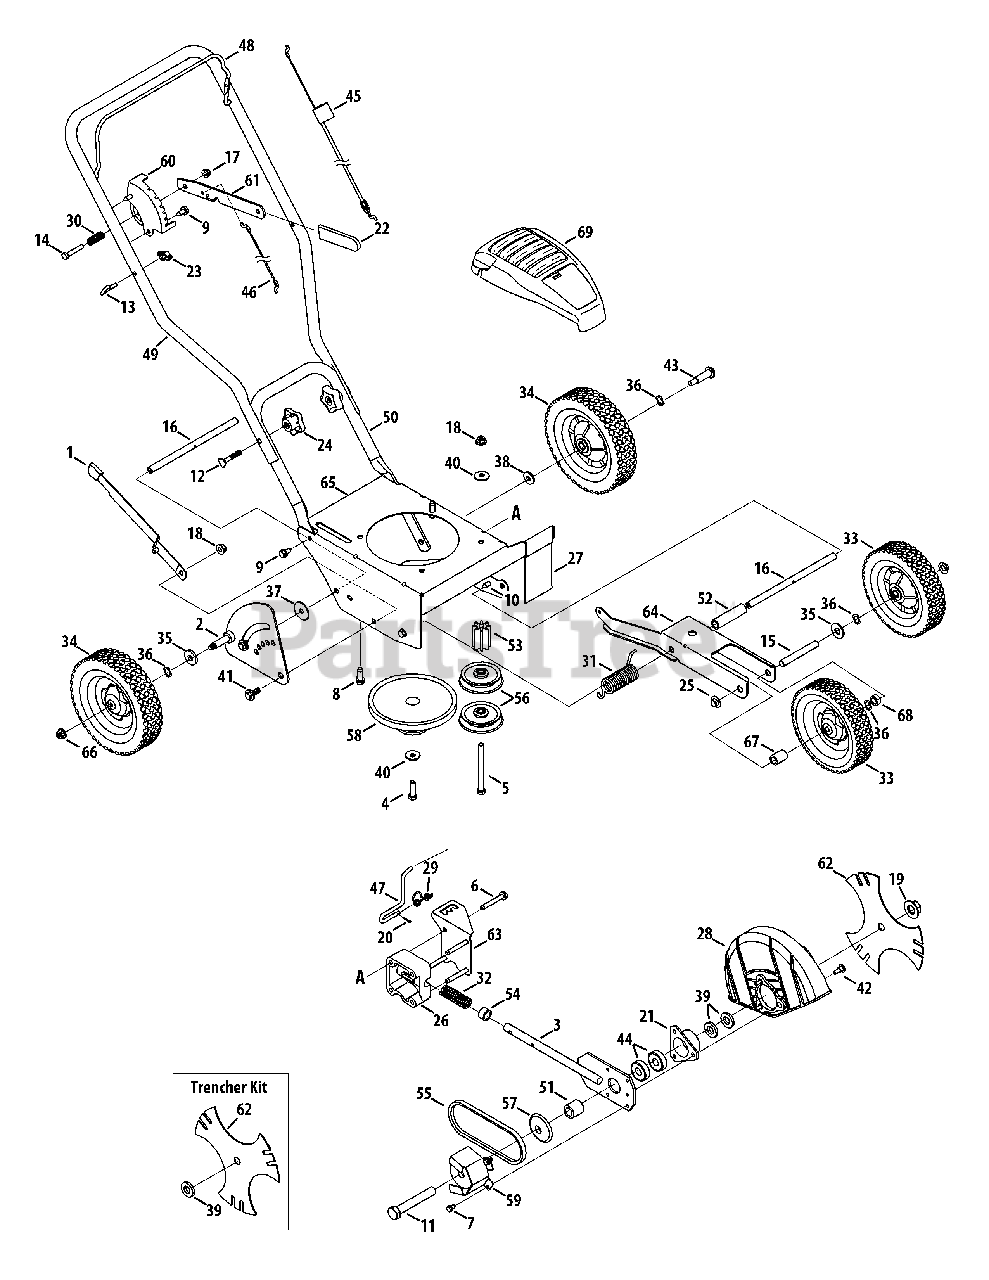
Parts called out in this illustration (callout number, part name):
1	Curb Height Adjustment Lever
2	Curb Height Adjuster Plate
3	Blade Plate Assembly
4	Screw 3/8-24
5	Screw 3/8-16
6	Hex Screw, 5/16-18
7	Self-tapping Screw, 1/4-20
8	Screw, 3/8-16
9	Hex Screw, 5/16-12
10	Hex Screw 5/16-18
11	Hex Screw, 5/8-18
12	Carriage Bolt, 5/16-18
13	Rope Guide (Eye Bolt)
14	Hex Screw, 5/16-18
15	Axle Shaft .50x6.65
16	Frame Spacer .50x9.25
17	Lock Flange Nut, 5/16-18
18	Flange Nut 3/8-16
19	Flange Nut, 5/8-18
20	Clevis Pin 3/32 x .625
21	Bearing Cup
25	Push Cap 1/2" rod
26	Bearing Block
27	Debris Guard
28	Blade Guard
29	Double Torsion Spring
30	Compression Spring
31	Torsion Spring
32	Compression Spring
33	Wheel 7 x 1.75 T-Tread
34	Wheel 8 x 1.75 T-Tread
35	Flat Washer, .531 x 1.25 x .181
36	Wave Washer .531 x .781 x .013
37	Flat Washer, .385 x 1.5 x .075
38	Flat Washer .385 x 1.0 x .135 †
39	Flat Washer .635x1.24x.181
40	Bell Washer,.396 x 1.140
41	Shoulder Screw, 3/8-16
42	Shoulder Screw
43	Shoulder Screw, 3/8-16
44	Bearing, .625 ID x 1.57 OD
45	Control Cable
46	Wheel Adjustment Cable
47	Blade Adjustment Rod
48	Bail Handle
51	Spacer, .63 x 1.12 x 1.06
53	Pulley Mount Spacer
54	Spacer, .64 x.88 x .50
56	Flat Idler Pulley, 2.5 OD
58	Combination Flywheel Pulley
61	Depth Index Lever
62	Tri-Star Blade
63	Bracket Plate
64	Dual Wheel Bracket
66	Flange Lock Nut, 3/8-16
67	Spacer., .525 x .775 x .93
68	Spacer., .505ID x .88OD x .440
69	Engine Shroud
69	Screw #10-16 x 1.25
